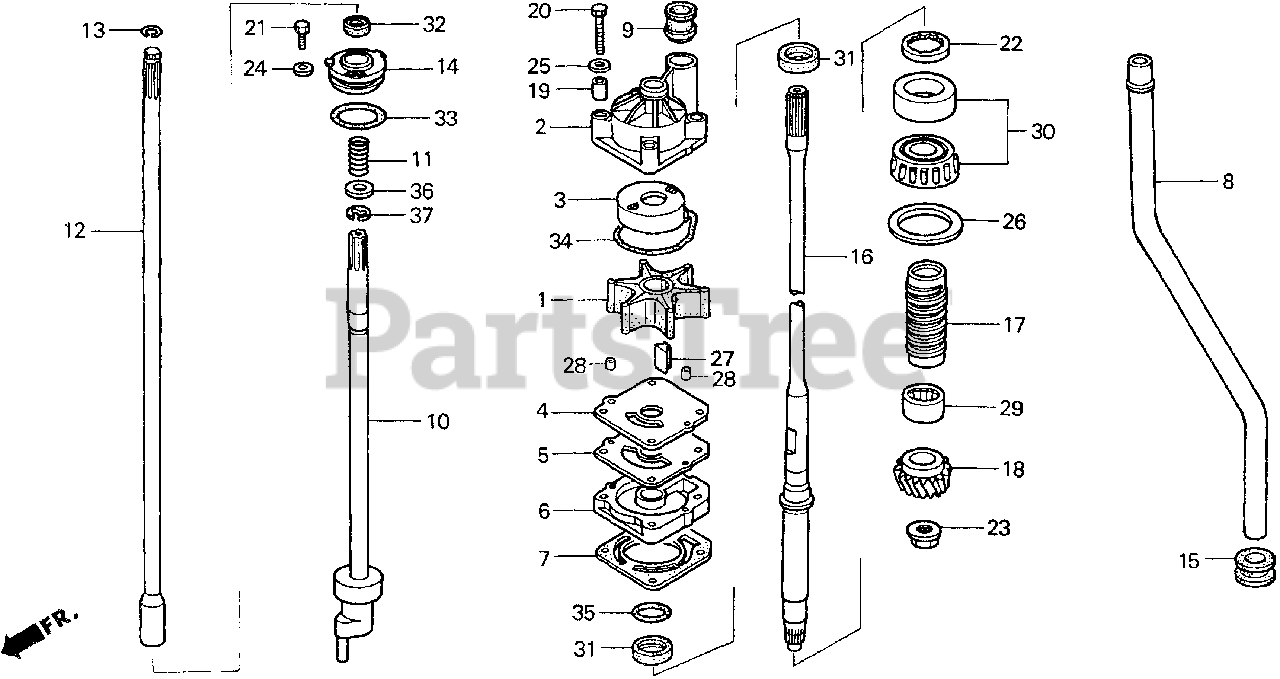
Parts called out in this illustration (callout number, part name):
1	IMPELLER, PUMP
2	HOUSING, IMPELLER
3	LINER, PUMP
4	COVER, IMPELLER
5	GASKET B, IMPELLER
6	HOUSING, WATER PUMP
7	GASKET, WATER PUMP
8	TUBE, WATER (L)
9	RING, WATER TUBE SEAL
10	ROD, SHIFT (L)
11	SPRING, SHIFT ROD
12	ROD A, SHIFT
13	RING, STOPPER
14	HOLDER, SHIFT ROD
15	GROMMET, EXTENSION CASE
16	SHAFT, VERTICAL
17	SLINGER, OIL
18	GEAR, PINION
19	COLLAR, DISTANCE
20	BOLT, HEX. (8X55)
21	BOLT, HEX. (6X12)
22	NUT, LOCK (64MM)
23	NUT, HEX. (18MM)
24	WASHER, PLAIN (6MM)
25	WASHER (8MM)
26	SHIM A, GEAR (0.10)
26	SHIM B, GEAR (0.15)
26	SHIM C, GEAR (0.30)
26	SHIM D, GEAR (0.50)
27	KEY, WOODRUFF
28	PIN, DOWEL (6X10)
29	BEARING, NEEDLE (1-1/2X1-1/4)
30	BEARING, TAPER ROLLER (30X62X21.25)
30	BEARING, TAPER ROLLER (30X62X40)
31	SEAL, WATER (23X36X6)
32	SEAL, WATER (10X21X6)
32	SEAL, WATER (12X21X6)
34	O-RING, WATER PUMP
35	O-RING (58.5X3.5)
36	WASHER, PLAIN (10MM)
36	WASHER, PLAIN (12MM)
37	E-RING (8MM)
37	E-RING (10MM)
